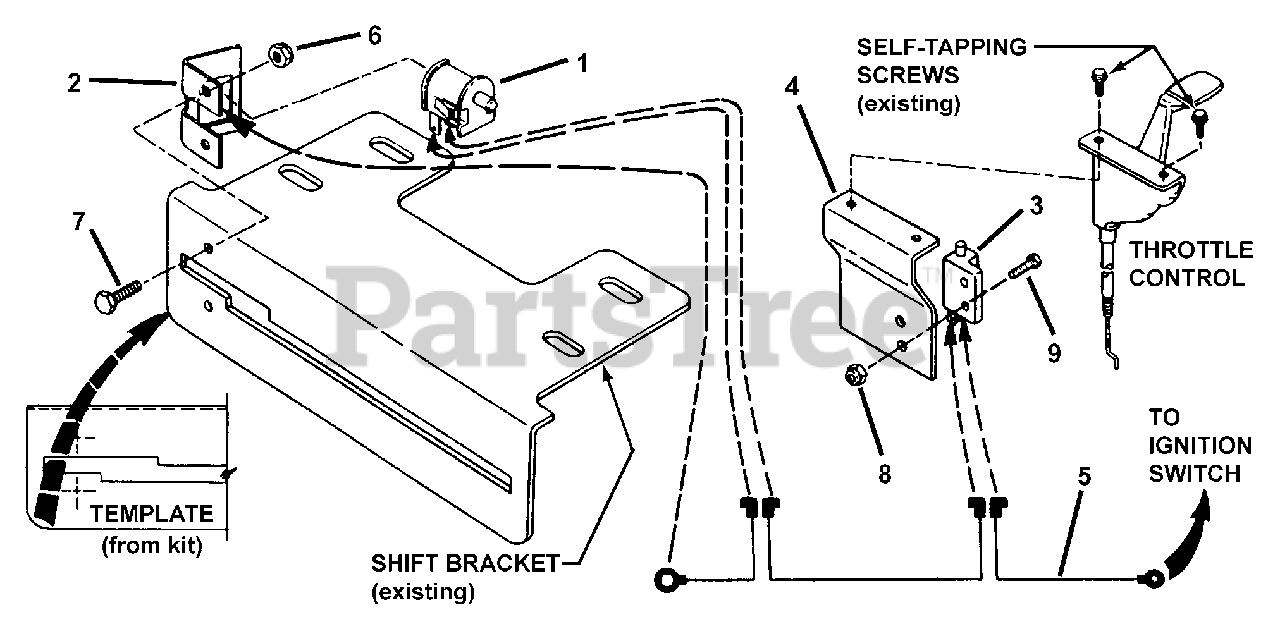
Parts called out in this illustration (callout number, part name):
1	SWITCH, Seat
2	BRACKET, Reverse Switch
3	SWITCH, Single Pole
4	BRACKET, Reverse Throttle
5	HARNESS, Reverse Throttle Wire
6	NUT, 1/4-20 Hex Nyloc
7	SCREW, 1/4-20 x 3/4" Hex Head Cap, Grade 5
8	NUT, #10-24 Hex Nyloc
9	SCREW, #10-24 x 1/2" Hex Head Cap
